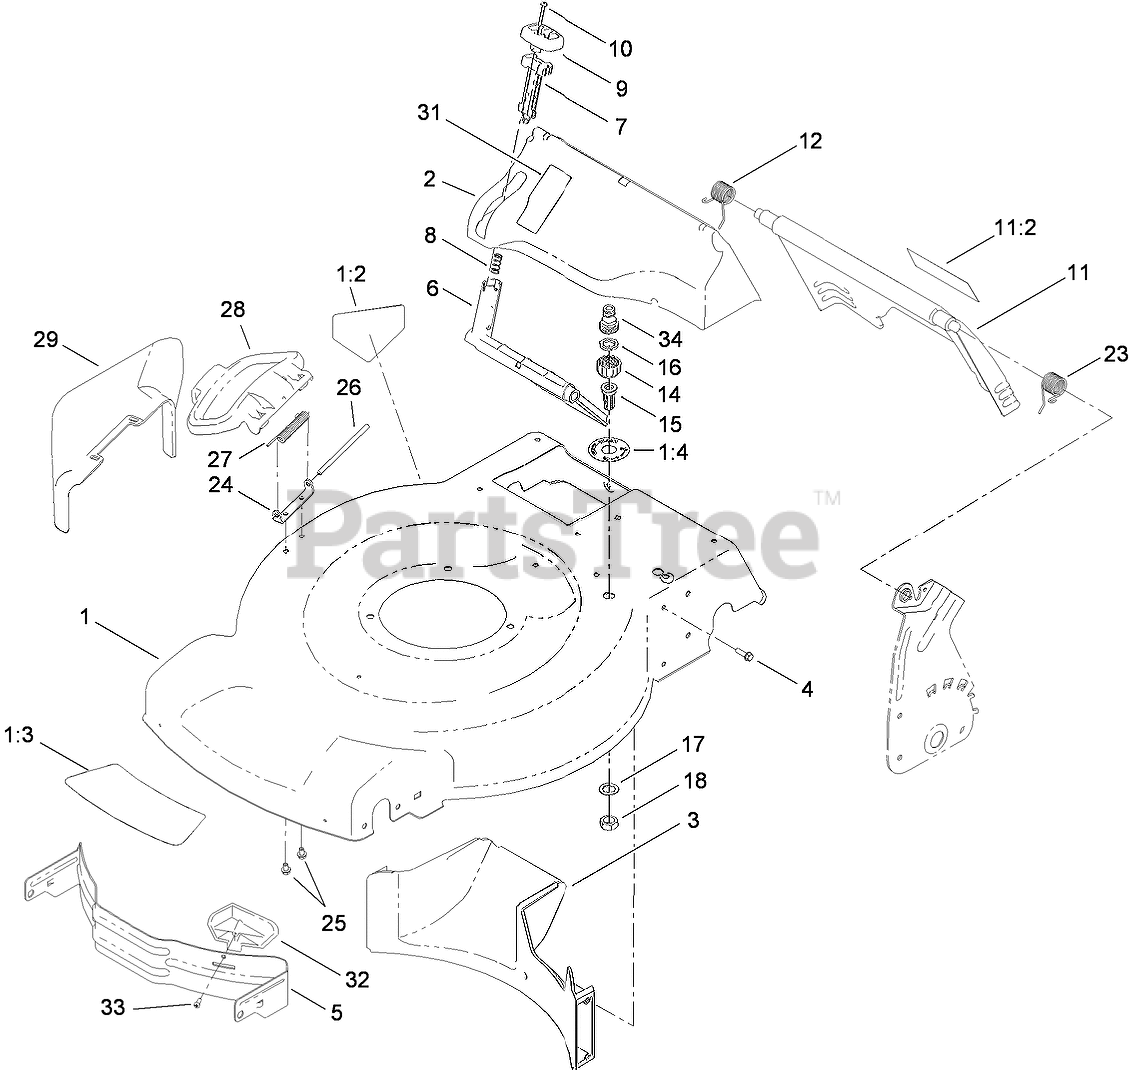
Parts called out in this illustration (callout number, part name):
1	HOUSING ASM
1:2	DECAL-DANGER
1:3	DECAL-RECYCLER
1:4	DECAL-PORT, WASHOUT
2	CHUTE-RECYCLE
3	BAFFLE-REAR
4	SCREW-HWH
5	BAFFLE-FRONT
6	DEFLECTOR-RECYCLE
7	LATCH-RECYCLE
8	SPRING-COMPRESSION
9	KNOB-RECYCLE
10	SCREW-PPH
11	REAR DOOR ASM
11:2	DECAL-WARNING
12	SPRING-TORSION
14	COUPLING-HOSE, WASHOUT PORT
15	PORT-WASHOUT
16	WASHER-SEAL, WASHOUT PORT
17	WASHER-TOOTH, INTERNAL
18	NUT-JAM
23	SPRING-TORSION
24	BRACKET-COVER
25	SCREW-HWH
26	ROD-COVER
27	SPRING-TORSION
28	DEFLECTOR-SIDE
29	CHUTE-DISCHARGE, SIDE
31	DECAL-BAG ON DEMAND
32	KICKER-FRONT
33	SCREW-PPH
34	ADAPTER-CONNECT, QUICK
